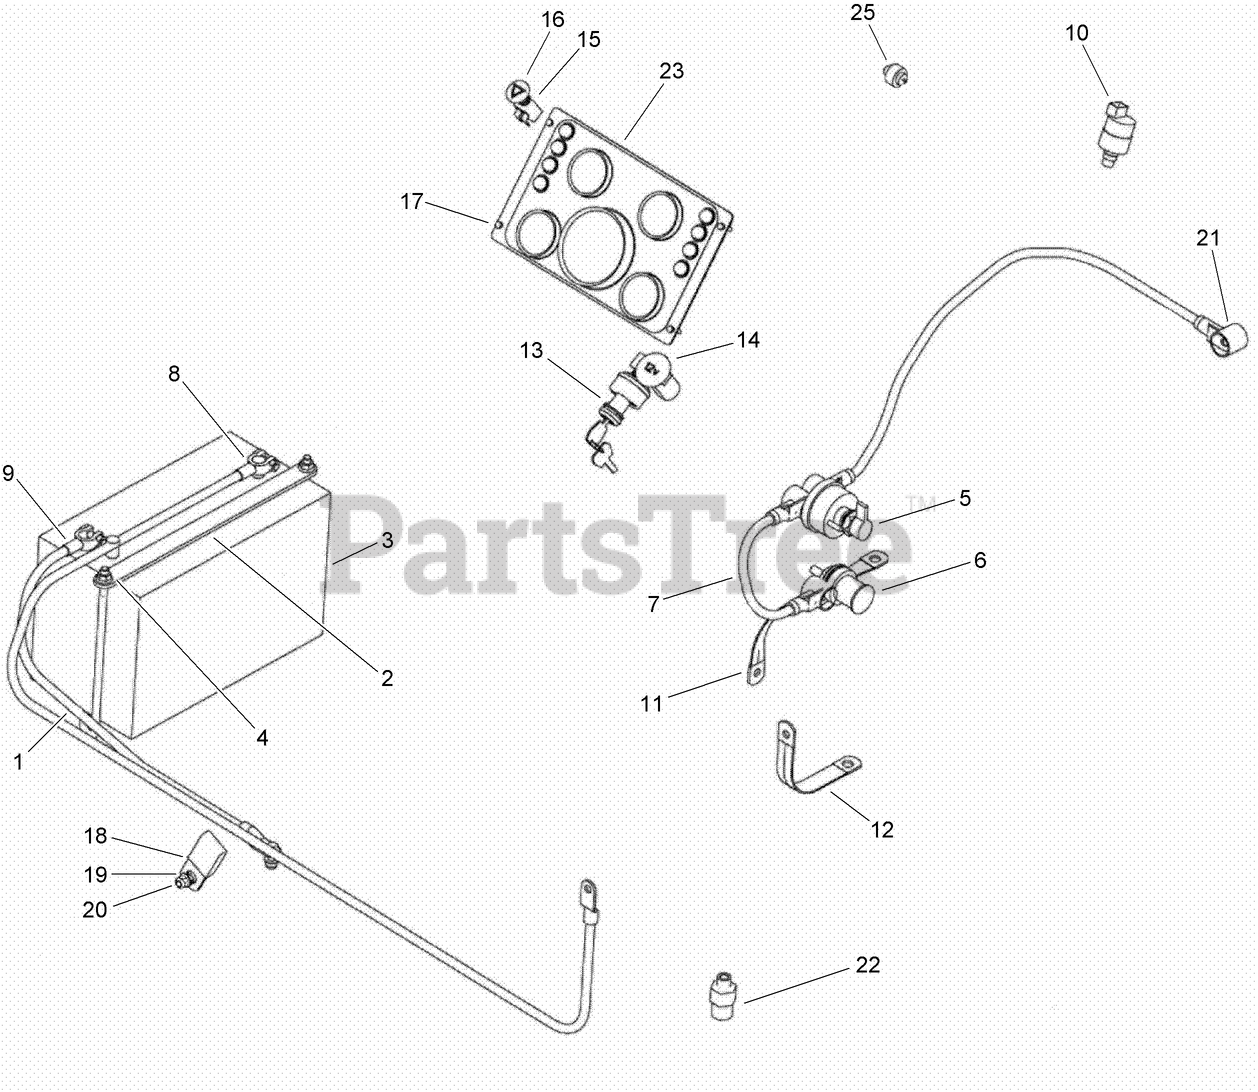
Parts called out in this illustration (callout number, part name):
1	BATTERY (purchase locally)
2	PLATE-Battery Hold Down
3	BOLT-HOLDDOWN, BATTERY
4	NUT-Serr Flg 3/8-16 UNC GR5 ZND
5	SWITCH-DISCONNECT, MASTER
6	POST-BATTERY, REMOTE
7	CABLE-Positive
8	CABLE-Positive
9	CABLE-Ground
10	SWITCH ASM
11	STRAP-GROUNDING
12	STRAP-GROUNDING
13	ASSEMBLY - Ignition Switch
14	RECEPTICAL-12V DC
15	SWITCH-Light
16	KNOB-Diff Lock
17	SCREW-HH
18	CLAMP-P Type 4 x 1/2
19	SCREW-HH
20	NUT-TORQUE, PREVAILING
21	CABLE-Battery, Positive
22	SWITCH-PRESSURE
23	INSTRUMENT PANEL ASM
25	SENDER-WATER TEMP
